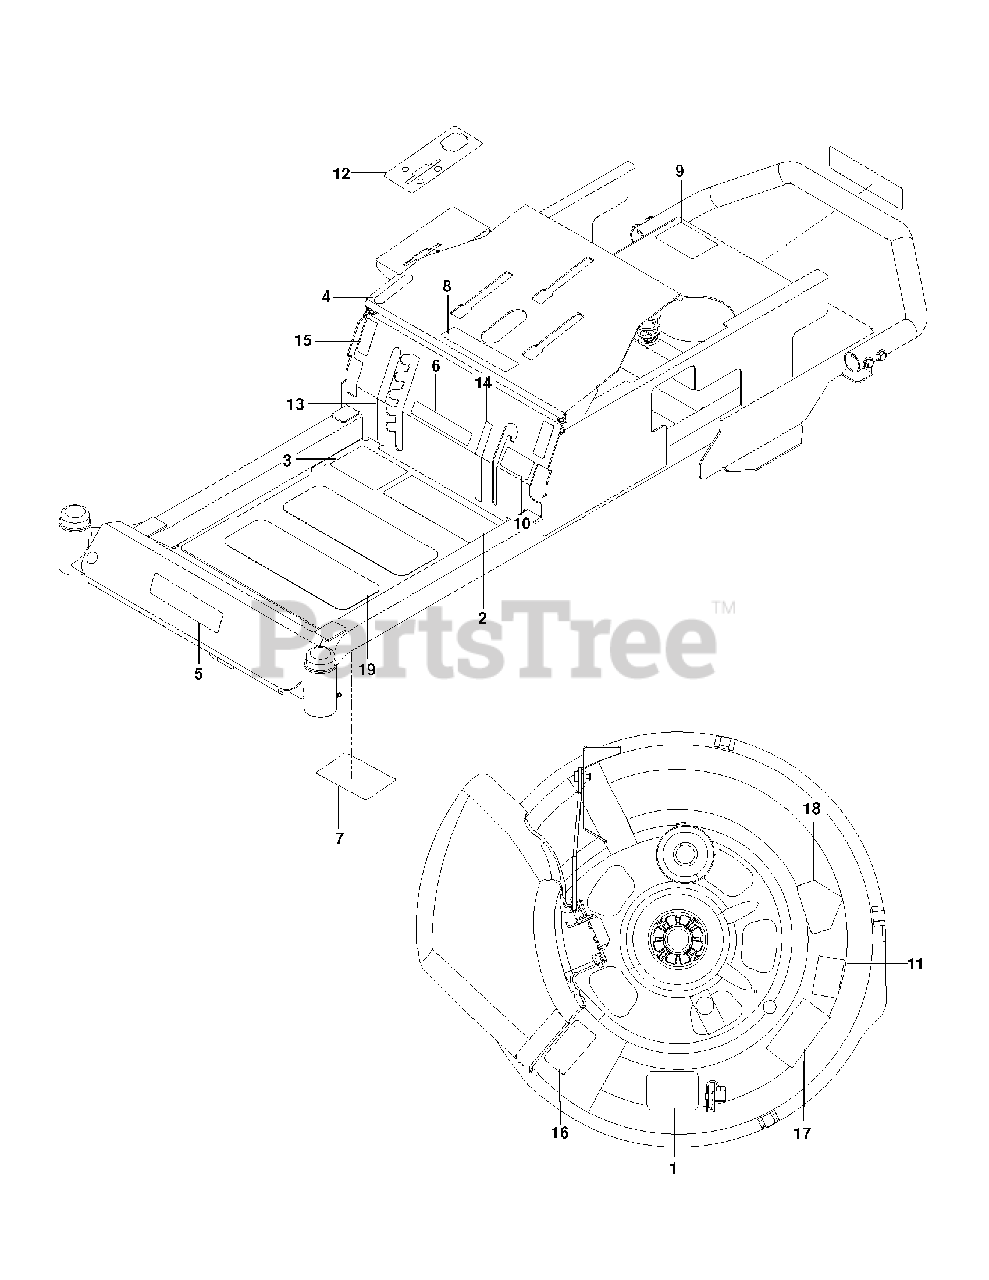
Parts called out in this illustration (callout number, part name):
1	DECAL, BELT ROUTING
2	DECAL, SAFETY WARNING
3	DECAL, WARNING
4	DECAL, PARK BRAKE
6	DECAL, SPEEDZTR 6.5"
7	DECAL, SERVICE
9	DECAL, DO NOT MOUNT
10	DECAL, FLAG
11	DECAL, 30, WHITE
12	DECAL, CONTROL PANEL
13	DECAL, DECK HEIGHT
14	DECAL, BLADE ENGAGEMENT
15	DECAL, MOTION CONTROL
17	DECAL, EURO SEVERING
18	DECAL, CPSC
19	ANTI-SKID PAD
